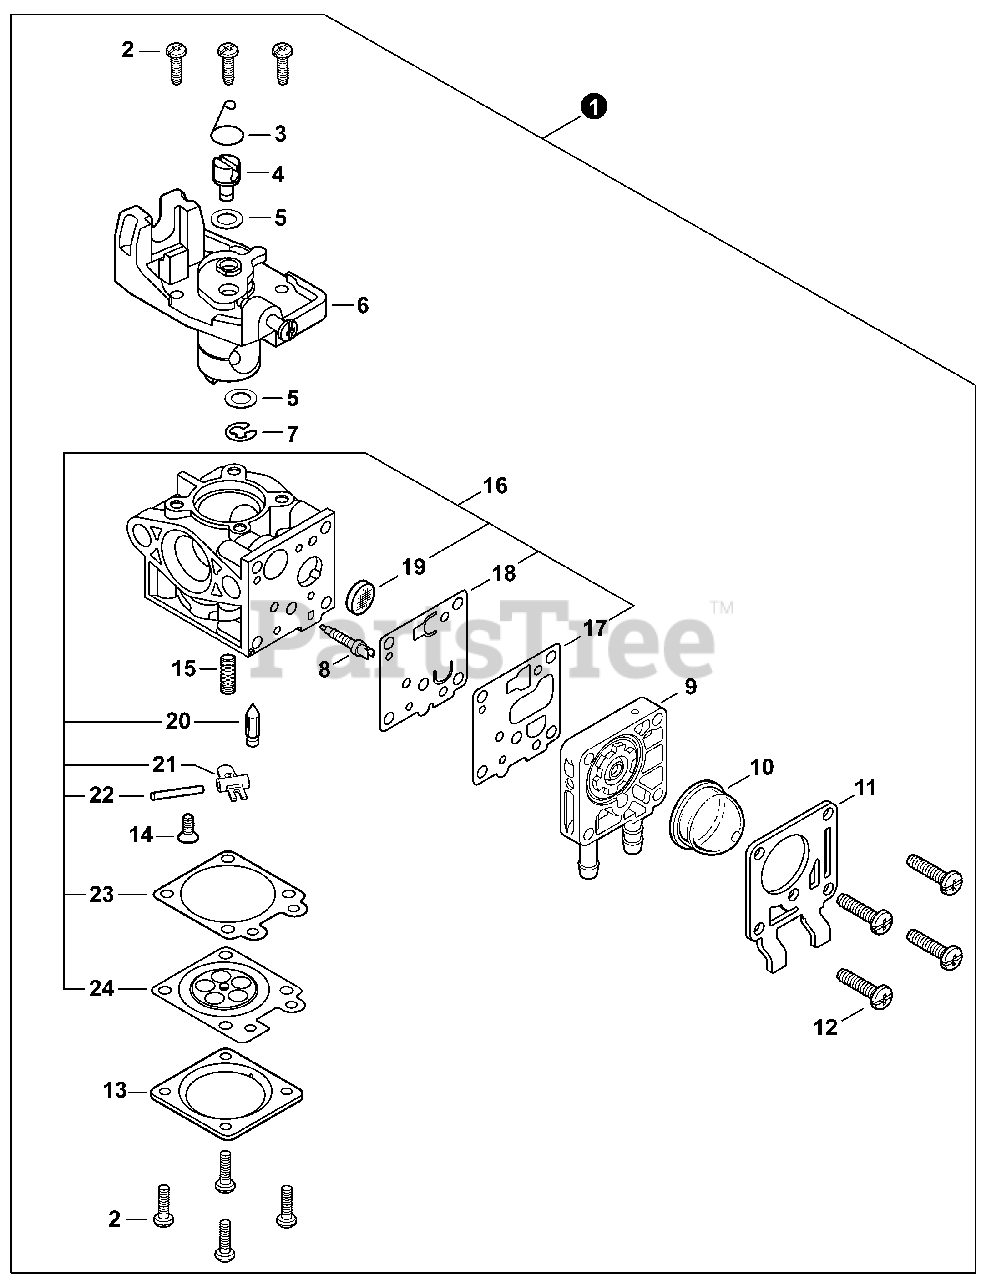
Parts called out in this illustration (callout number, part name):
1	CARBURETOR - WYG-14
6	THROTTLE VALVE ASSY
8	NEEDLE, MIXTURE
9	BODY ASSY, PUMP
10	BULB, PURGE
11	COVER, FUEL PUMP
13	COVER, METERING DIAPHRAGM
16	REPAIR KIT, CARBURETOR
17	GASKET, FUEL PUMP
18	DIAPHRAGM, FUEL PUMP
19	SCREEN, FUEL INLET
20	VALVE, INLET NEEDLE
21	LEVER, METERING
22	PIN, METERING LEVER
23	GASKET, METERING DIAPHRAGM
24	DIAPHRAGM, METERING
